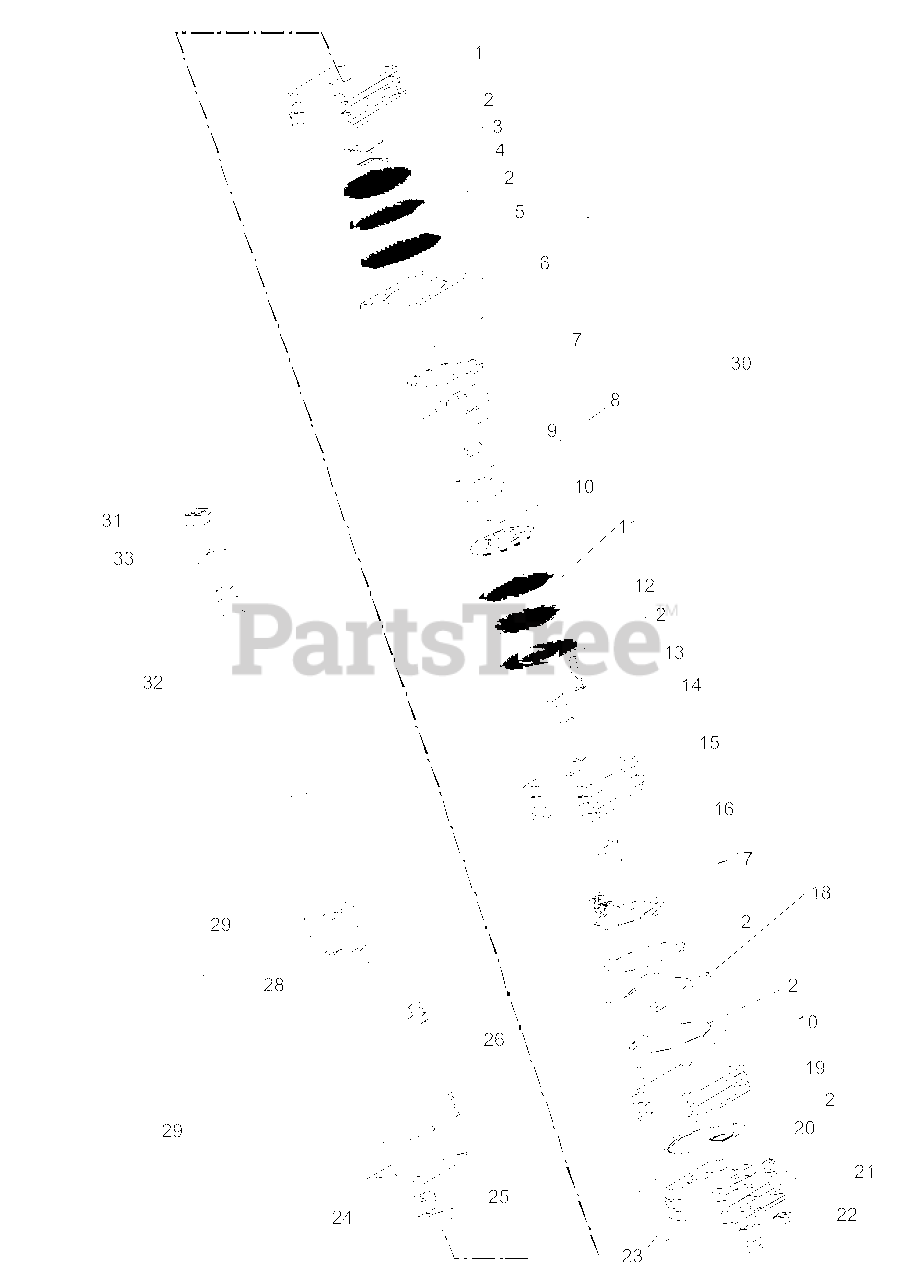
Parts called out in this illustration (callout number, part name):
1	Upper Cover Plate
2	Repair Kit
3	Seal Spacer
4	Thrust Bearing
6	Metering Ring
7	Drive Plate
10	Needle Roller Service Assembly
11	Commutator & Ring Assembly
12	Commutator Cover
13	Screw-Special Ross
14	Drive Link
15	Isolation Manifold
16	Hex Drive
17	Spring Service Assembly
18	Valve & Ring Assembly
19	Port Manifold
20	Ball-Steel
21	Plug & O-Ring Assembly
22	Nut-Locking-Center .312-24
23	Port Cover
25	Ring-Retaining Ross
26	Stud-Special SV Ross
27	Input Shaft Service Assembly
28	Column Bearing Set
30	Metering Assembly
31	Nut-Locking-Nylon .625-18
32	Upper Cover & Jacket Tube Assembly
33	Dust Cover
